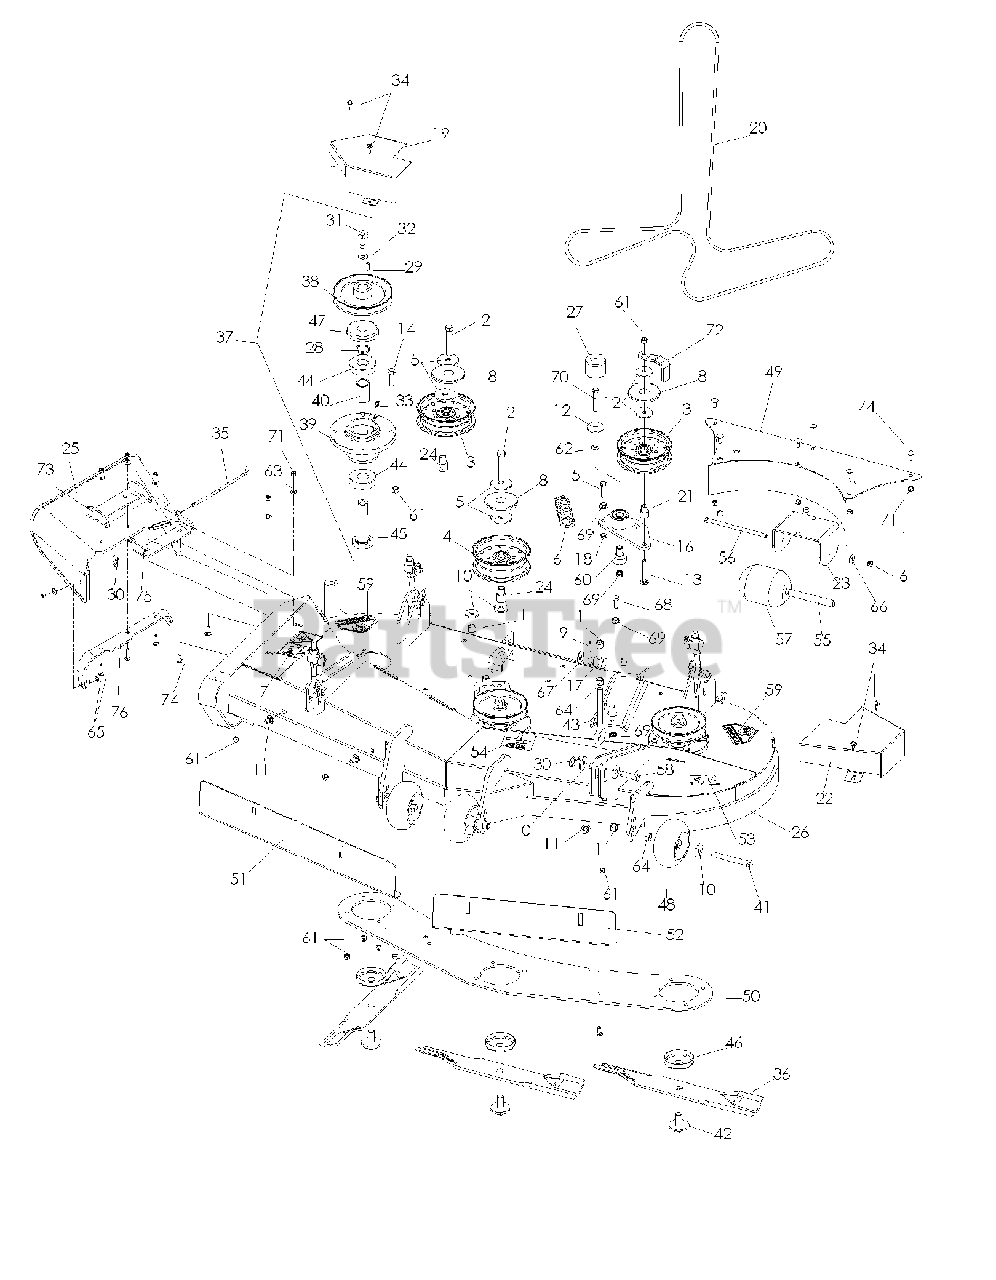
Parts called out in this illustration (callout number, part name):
1	NUT 1/2-13 HEX NYLOC ZD
2	SCREW, 1/2C X 3 HEX CAP
3	IDLER PULLEY
4	IDLER PULLEY (TALL)
5	ISOLATOR WASHER
6	DECK SPRING
7	DECAL, EURO SEVERING
8	TOP DUST CAP
9	PIN COTTER 1/8 X 1 ZD
10	WASH USS FLAT 1/2
11	RHSNB 3/8-16 X 3/4 GR5 ZD
12	WASHER, 3/8 SPEC
13	RHSNB 3/8-16 X 2.75
14	HCS 3/8C X 1 1/2
15	HCS 3/8-16 X 1-1/2
16	ARM-IDLER W/BRG
18	NUT 3/8-16 HEX JAM
19	PULLEY GUARD RH BLACK
20	BELT-DECK, 52
21	BUSHING, IDLER
22	PULLEY GUARD 52 LH BLACK
23	REAR CENTER ROLLER BKT 52 CLK
24	SPACER - IDLER
25	CHUTE, RUBBER DISCHARGE 52"
26	DECK W/DECAL 52 GRIZZLY
27	CAP, VINYL
28	HUB PULLEY SPACER
29	KEY - 1/4 X .88
30	PIN, COTTER 1 3/4
31	1/2-20 UNF X 1 1/4 HHBLT
32	WASHER .525 X 1.375 X .25
33	ZERK, 3/16, DRIVE IN
34	SCREW, TAP & DR #12-14 X 3/4
35	DEFLECTOR PIN
36	BLD 52HFS HI LIFT FUS
37	SPINDLE ASM.
38	METRIC PULLEY
39	DECK HUB MACHINED
41	HCS 1/2-13 X 4 GR 5 ZD
42	BLADE BOLT/WASHER
43	BOLT, EYE
44	BEARING - 6305 - 2RS
45	SHAFT SHORT
46	TRASH GUARD
47	TRASH GUARD
48	GAUGE WHEEL
49	W-BAFFLE WLDT.
50	HUB STIFFENER PLATE
51	BLOW-BY BAFFLE 52` LH
52	BLOW-BY BAFFLE 52` RH
53	DECAL, 52"
54	DECAL, BELT ROUTING (18656)
55	BUSHING
56	3/8-16 X 6-1/2 HHB GR8
57	ROLLER 3-3/4 DIA. X 4-1
58	CLEVIS PIN 1/2X1-3/4LG
59	DECAL, CPSC
60	PIVOT, BEARING
61	NUT 3/8-16 NYLOC
62	WASHER 3/8 SAE FLAT
63	FLAT WASHER 5/16 SAE
64	NUT HEX 1/2
65	RHSNB 5/16-18 X 1-1/2 GR 5 ZD
66	WASHER 3/8 FLAT
67	WASHER 1/2 FLAT
68	HCS 3/8C X 1
69	NUT 3/8C WHIZ
70	HCS 3/8C X 2 1/2
71	NUT 5/16 NYLOC
72	SLW 3/8 STD
73	PIVOT BRKT RUBBER CHUTE
74	RHSSNB 5/16C X 1.0
75	PIVOT BRACKET - DECK
76	BRACKET, REINF - CHUTE
